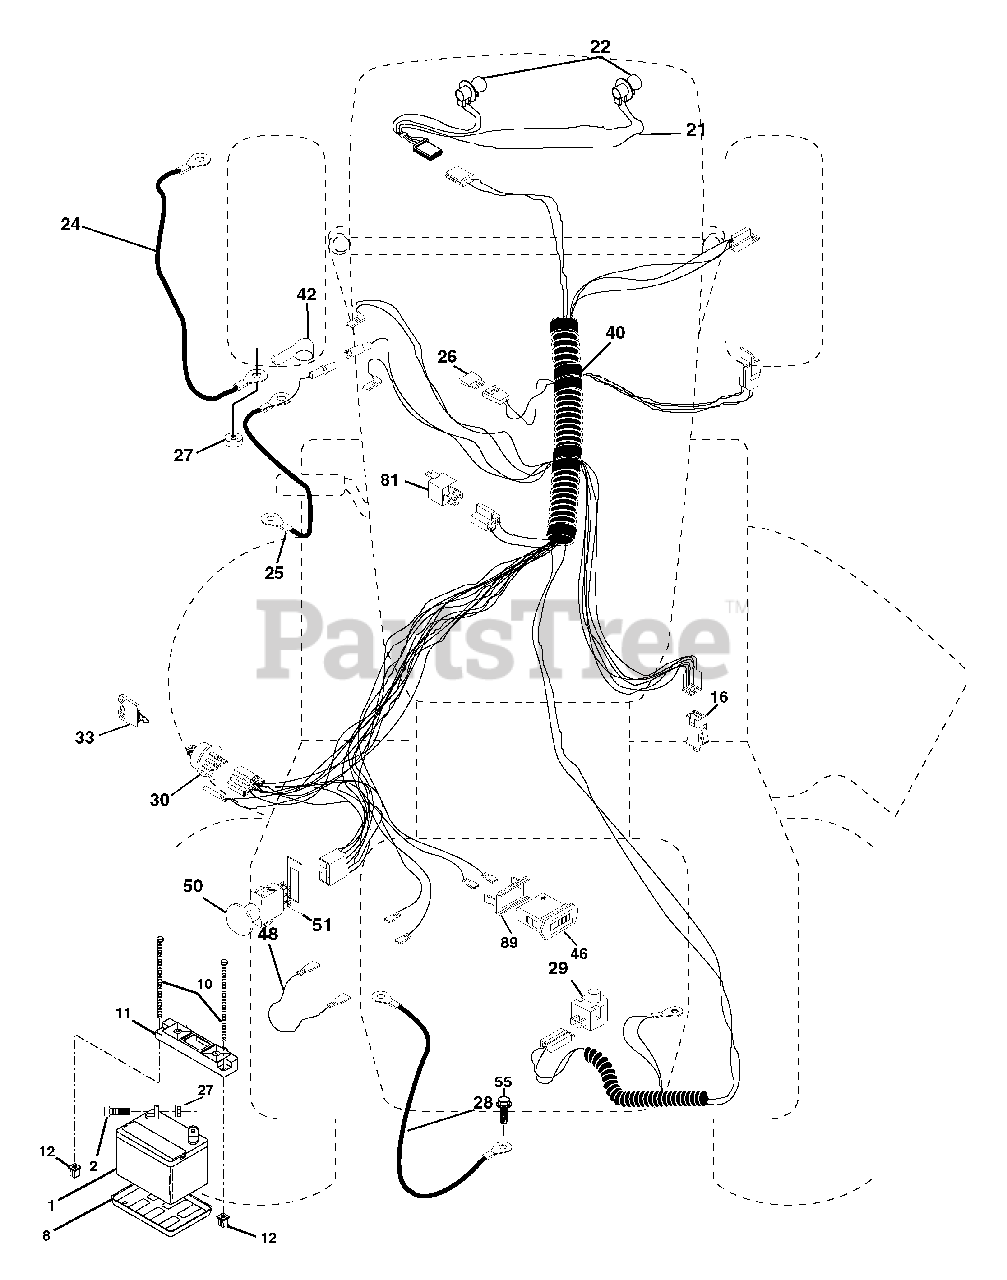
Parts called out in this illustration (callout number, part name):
1	Battery
2	Bolt Hex Hd 1/4-20unc X 3/4
8	Tray Battery
10	Bolt Brt Frt 1/4-20 x 75 Ainc
11	Holddown Battery Front Mount
12	Nut Push Nylon 1/4 Battery Frt
16	Switch Interlock Push-In
21	Harness Asm Light W/4152j
22	Bulb Light #1156
24	Cable Battery 6 Ga 22 red w/16 wire
25	Cable Battery 6 Ga 11 red
27	Nut Flange, M8 x 1.25
28	Cable Ground 6 Ga 21 black
29	Switch Plunger Nc Gray
30	Switch Ign
33	Key Ign Molded Generic
40	Harness Ign.
42	Cover, Terminal, Red
46	Meter Hour
48	Adapter Ammeter
50	Switch PTO
51	Ring Retainer PTO
55	Screw Thdrol 5/16-18 x 1-1/2 Tyt
81	Relay Asm.
89	Bracket Snap-In Hourmeter
